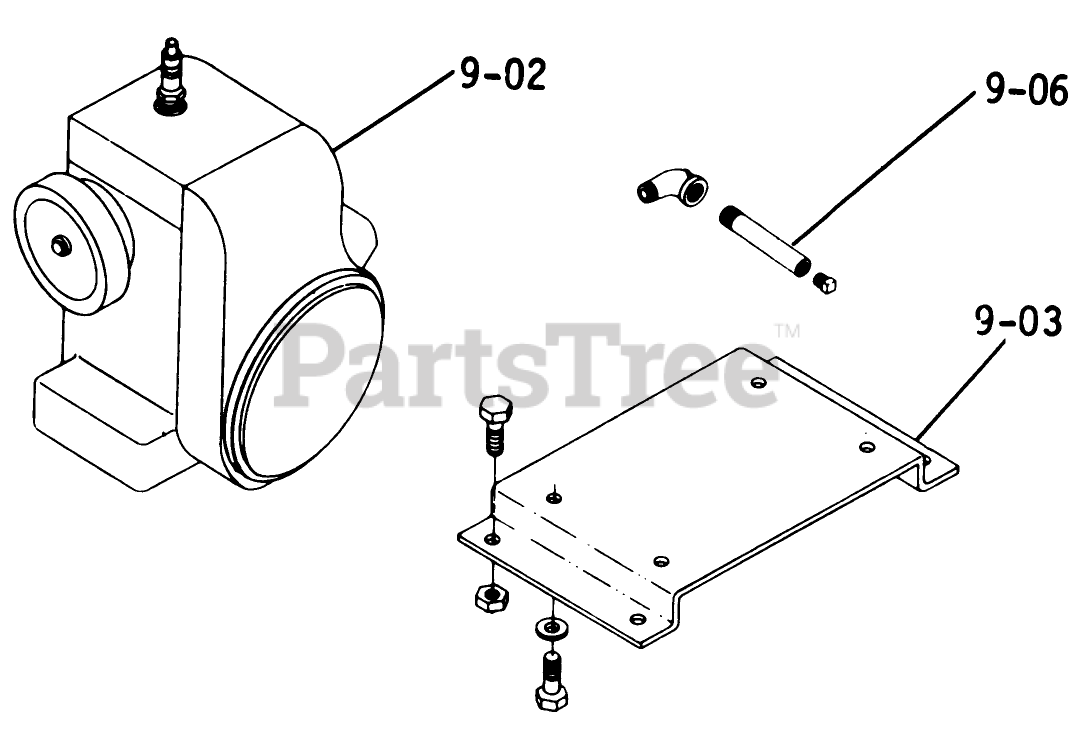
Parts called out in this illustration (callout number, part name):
9-02	Engine-8HP Kohler
9-03	Engine Base
9-06	Nipple 3/8 x 5
